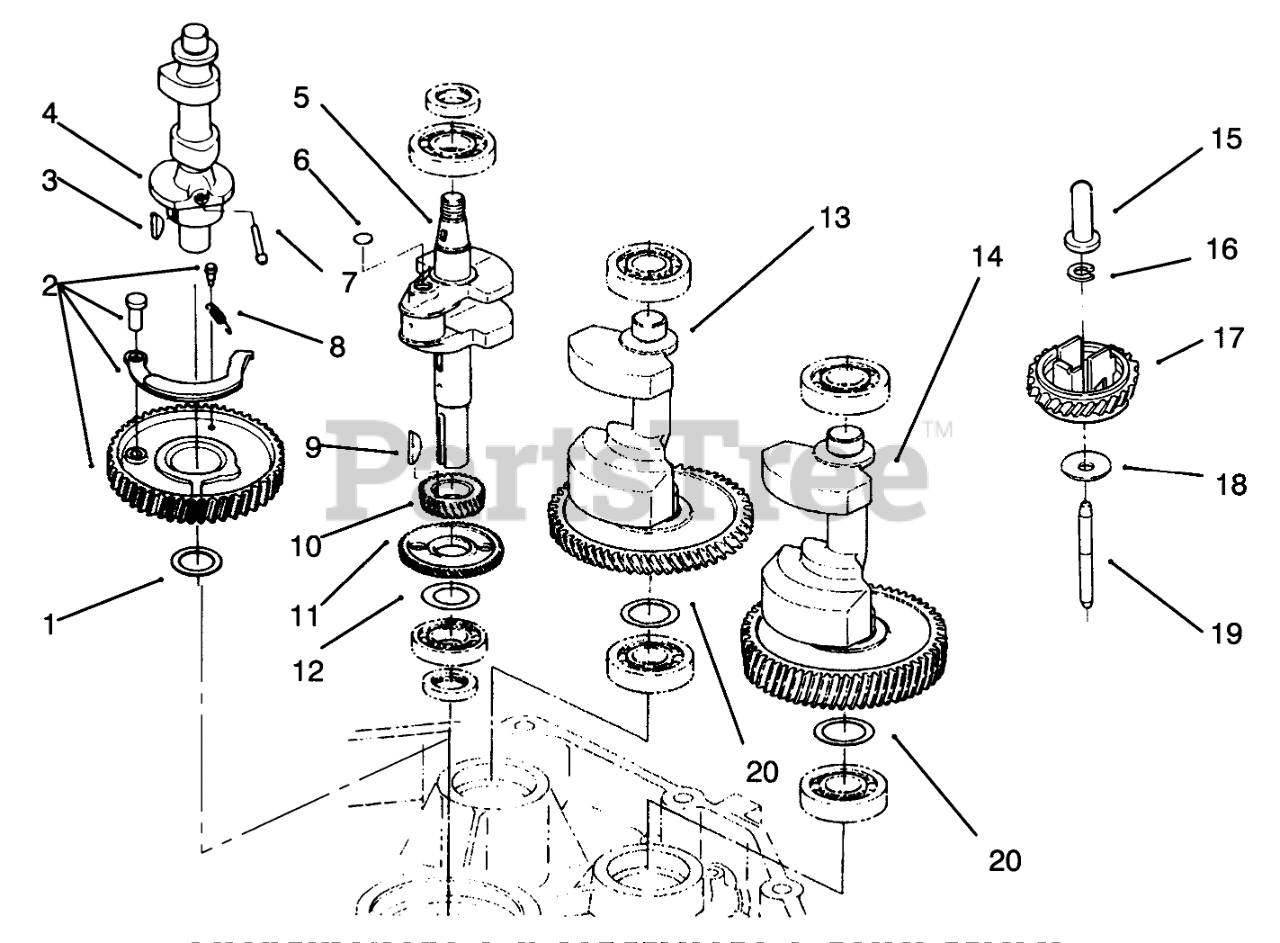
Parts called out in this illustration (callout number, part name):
1	SHIM-CAMSHFT 0.5MM
2	CAMGEAR ASS'Y
3	KEY-CAMGEAR
4	Camshaft Assembly (Incl. Ref. #1-3, 7 & 8)
5	CRANKSHAFT ASM
6	PLUG-EXPANSION
7	PIN-DECOMPRESSION
8	SPRING-DECOMPRESSION
9	KEY-CRANKSHAFT GEAR
10	GEAR-CRANKSHAFT
11	GEAR-BALANCER
12	SHIM-CRANKSHFT 0.2MM
13	BALANCER SHAFT ASM
14	BALANCER SHAFT ASM
15	GOVERNOR SLEEVE
16	GOV GEAR RETAINER
17	GEAR-GOVERNOR
19	PARALLEL PIN
20	BALANCER SHAFT SHIM
